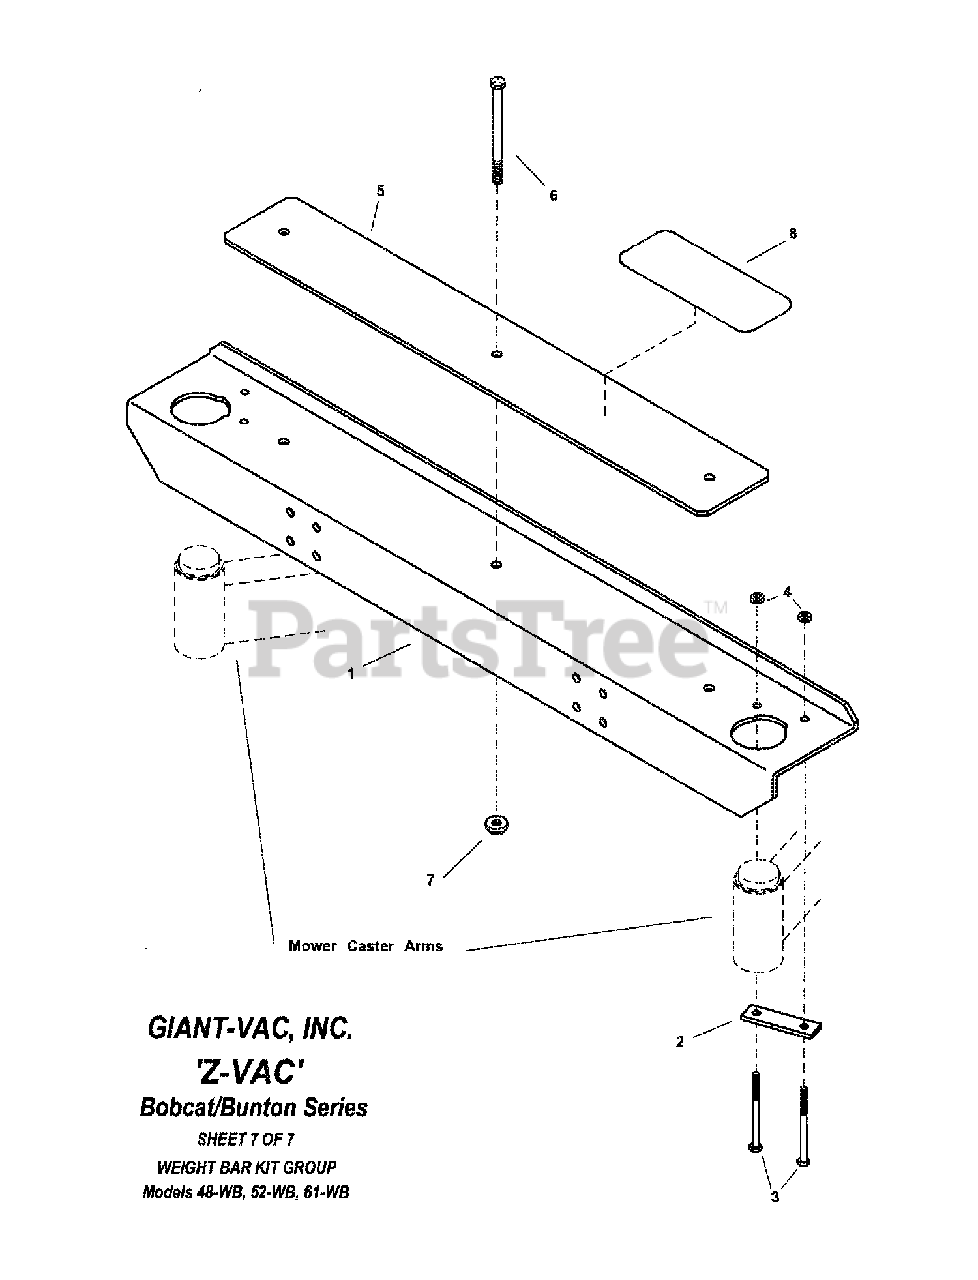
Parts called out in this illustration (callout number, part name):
1	CHANNEL, Weight Mount, 48" Bobcat
1	CHANNEL,Weight Mount, 52" Bobcat
1	CHANNEL, Weight Mount, 61" Bobcat
2	BAR, Clamp
3	SCREW, 3/8-16 x 3-1/4" Hex Head Cap, G5
4	NUT, 3/8-16 Hex Top Lock
5	WEIGHT BAR, 48" & 52" Bobcat
5	WEIGHT BAR, 61" Bobcat
6	SCREW, 1/2-13 x 3-1/2 Hex Head Cap
6	SCREW, 1/2-13 x 3" Hex Head Cap
7	NUT, 1/2-13 Hex Flange Lock
8	PAD, Anti-Skid, Weight Kit
